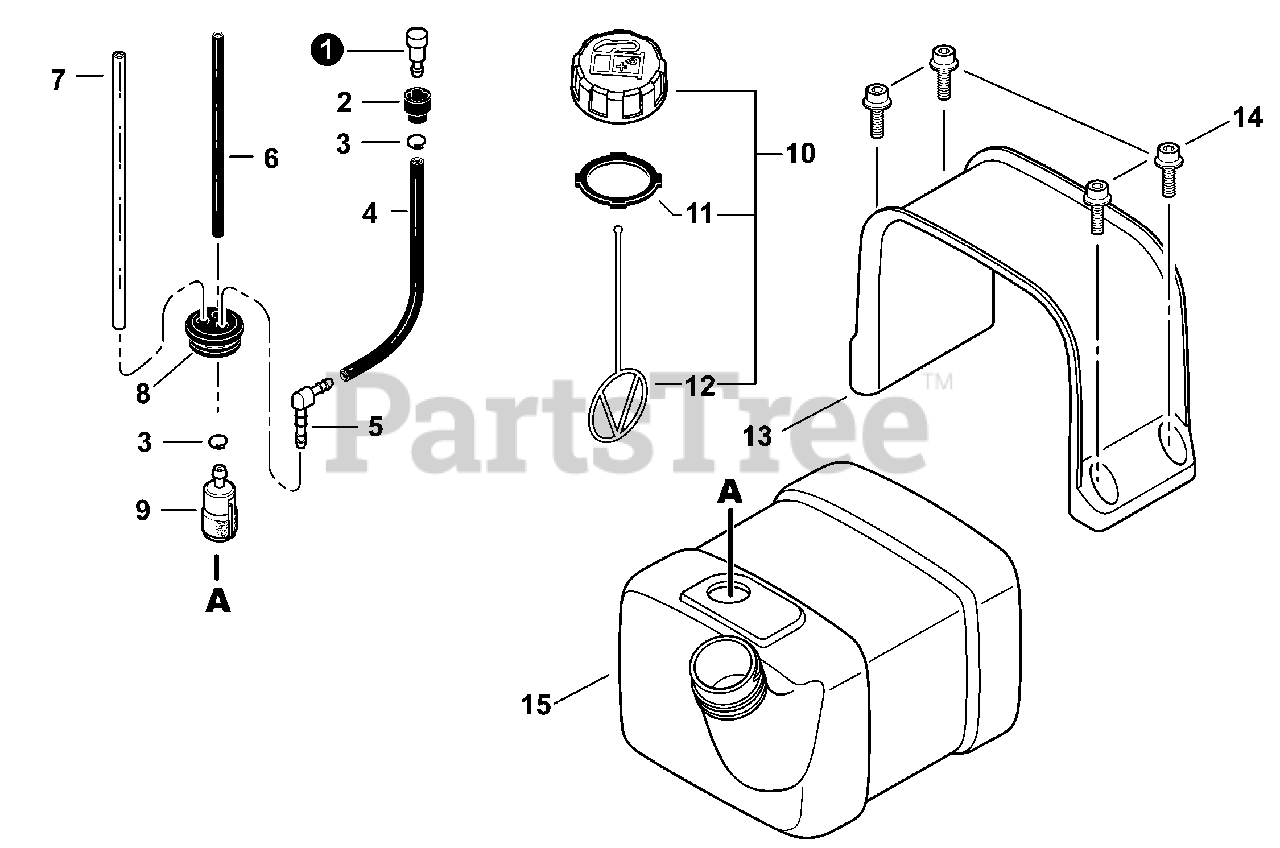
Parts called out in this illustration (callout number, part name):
1	VENT ASSY
2	HOLDER, VENT
3	CLIP 6.5 MM
4	PIPE, VENT 3×6×145 MM
5	CONNECTOR, PIPE Ø5.4
6	PIPE, FUEL 3×6×230
7	PIPE, FUEL RETURN 3×6×145
8	GROMMET, FUEL
9	FILTER, FUEL 125-528
10	CAP ASSY, FUEL
11	GASKET, FUEL CAP
12	CONNECTOR, CAP L= 100 MM
13	BRACKET, FUEL TANK
14	BOLT 5×16
15	TANK, FUEL
